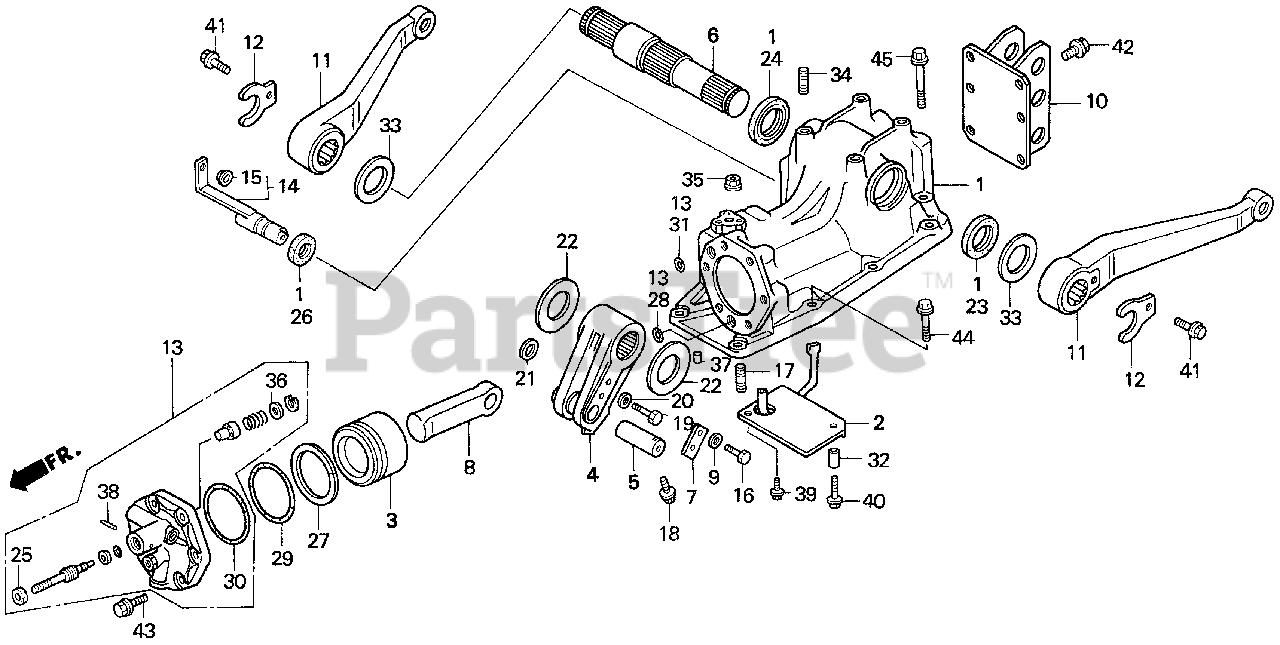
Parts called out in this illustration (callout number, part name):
1	CYLINDER, HYDRAULIC
2	PIPE, DRAIN
3	PISTON, HYDRAULIC (70MM)
4	ARM, HYDRAULIC CYLINDER
5	PIN, CONNECTING ROD
6	SHAFT, HYDRAULIC CYLINDER
7	PLATE, CONNECTING ROD PIN
8	ROD, HYDRAULIC CYLINDER CONNECTING
10	BRACKET, TOP LINK
12	STOPPER, LIFT ARM
13	CYLINDER HEAD ASSY., HYDRAULIC
14	SHAFT, POSITION CONTROL
15	BUSH (12X7)
16	BOLT, HEX. (6MM)
17	BOLT, STUD (10X28)
18	BOLT, STOP (6X14)
19	BOLT, POSITION CONTROL SHAFT
20	WASHER, CONICAL SPRING (8MM)
21	WASHER, THRUST (17.2MM)
22	WASHER, PLAIN (38X64)
23	OIL SEAL (40X52X5)
24	OIL SEAL (35X50X6)
25	OIL SEAL (8X16X5)
26	OIL SEAL (20X35X8)
27	RING, BACK-UP
28	O-RING (8.8X1.9)
29	O-RING (59.6X5.7)
30	O-RING (64.4X3.1)
31	O-RING (11.8X2.4)
32	COLLAR (7X14X28)
33	WASHER (36X60X1.5)
34	BOLT, STUD (10X25)
35	NUT, FLANGE (10MM)
36	WASHER, PLAIN (8MM)
37	PIN C, DOWEL (8X14)
38	PIN, SPRING (4X25)
39	BOLT, FLANGE (6X12)
40	BOLT, FLANGE (6X40)
41	BOLT, FLANGE (8X20)
42	BOLT, FLANGE (10X20)
43	BOLT, FLANGE (10X30)
44	BOLT, FLANGE (10X35)
45	BOLT, FLANGE (10X65)
